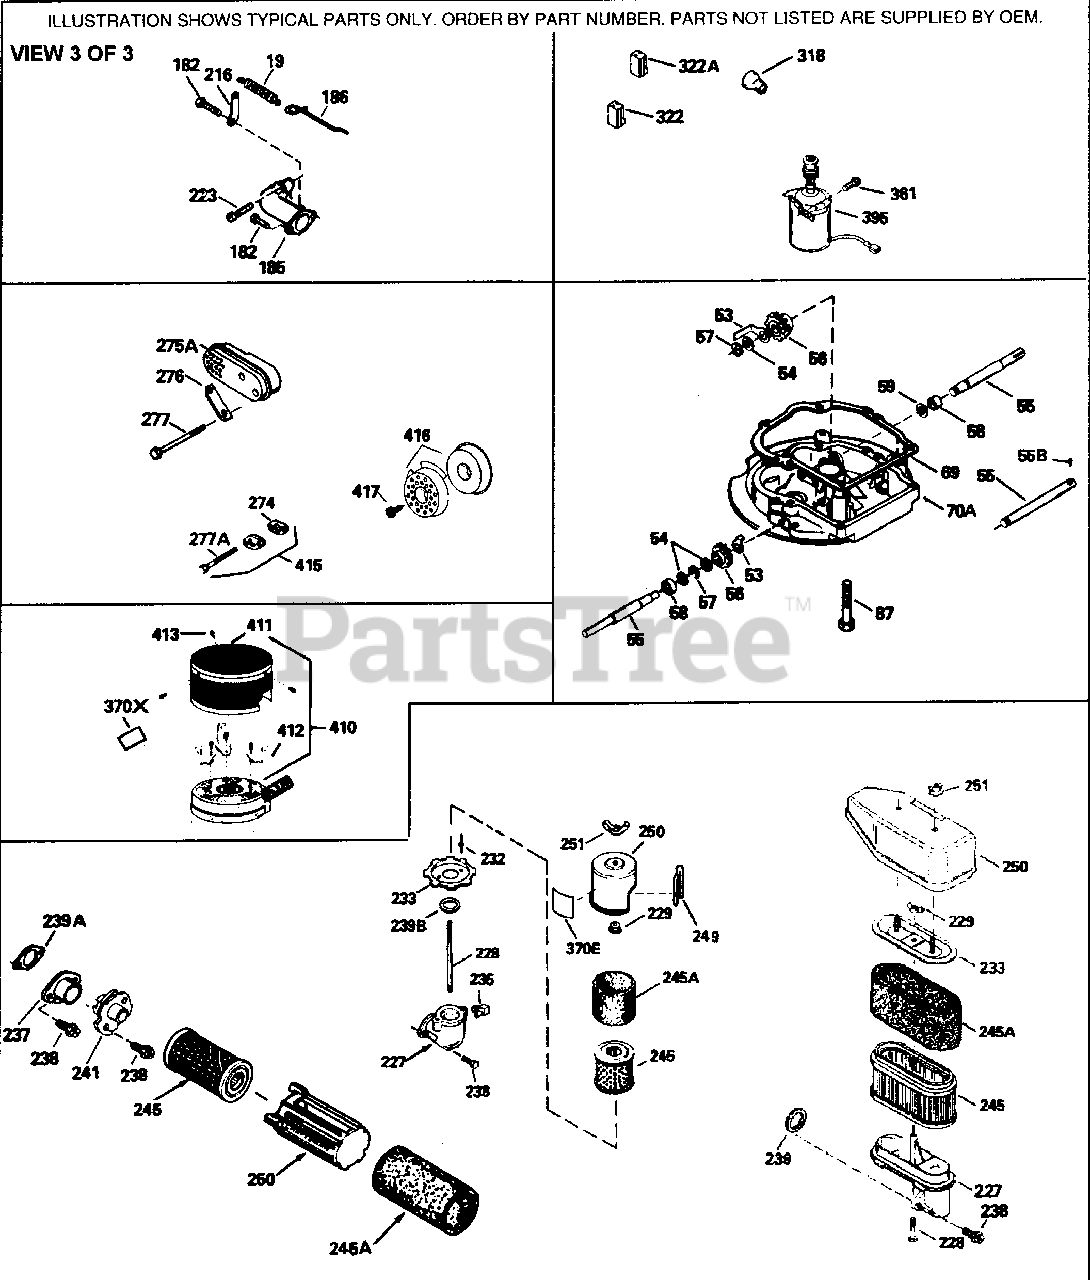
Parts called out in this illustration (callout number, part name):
19	Extension Spring
69	* Mounting Flange Gasket
182	Screw, 1/4-28 x 7/8"
185	Intake Pipe (Incl. 224)
186	Governor Link
223	Screw, 1/4-20 x 1"
227	Air Cleaner Elbow Ass'y Incl. 235 &24 3
228	Stud, 1/4-20 x 6.20"
229	Nut & Lockwasher, 1/4-20
233	Air Cleaner Bracket
235	Air Cleaner Elbow Fitting
238	Screw, 10-32 x 3/4"
239A	Air Filter Gasket
239B	Air Cleaner Gasket
245	Air Filter
245A	Air Filter
249	Air Cleaner Cover Seal
250	Air Cleaner Cover (chrome)
251	Wing Nut, 1/4-20
275A	Muffler (Incl. 277)
276	Locking Plate
277	Screw, 1/4-20 x 2-1/4"
370E	Instruction Decal
